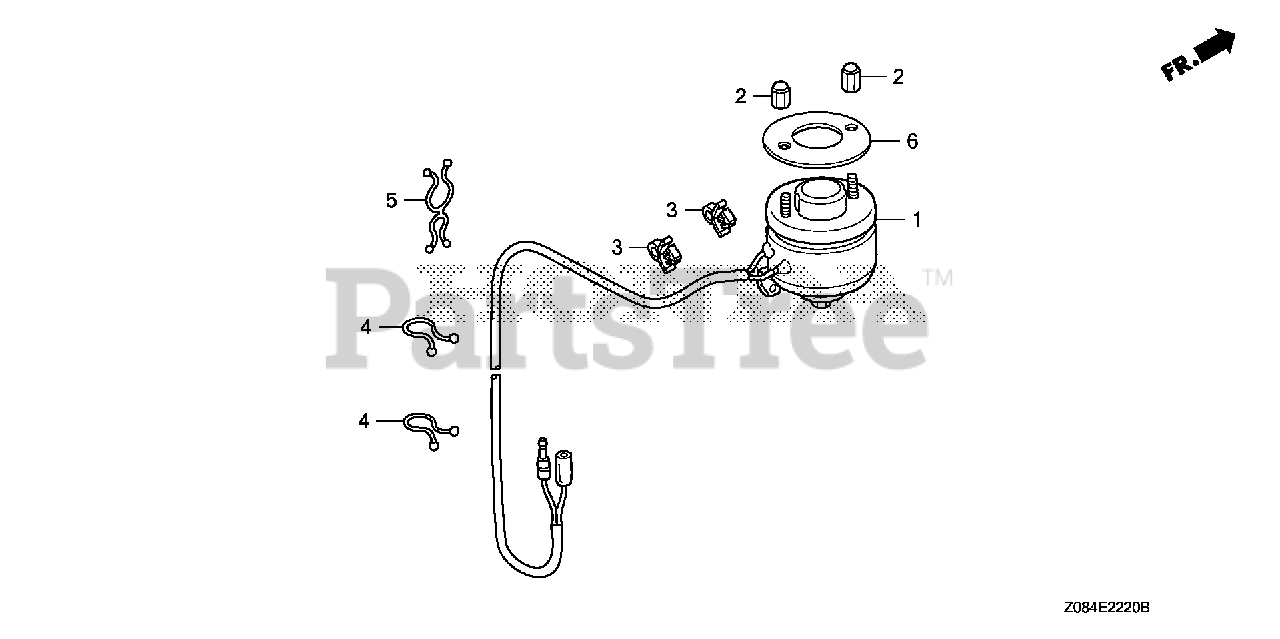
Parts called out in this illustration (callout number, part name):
1	SOLENOID ASSY., ROTARY
2	NUT, SPECIAL CAP
3	CLIP, WIRE HARNESS (6MM) (WHITE)
4	PURSE, LOCK (8MM)
5	CLIP, PURSE LOCK
6	PLATE, SOLENOID
